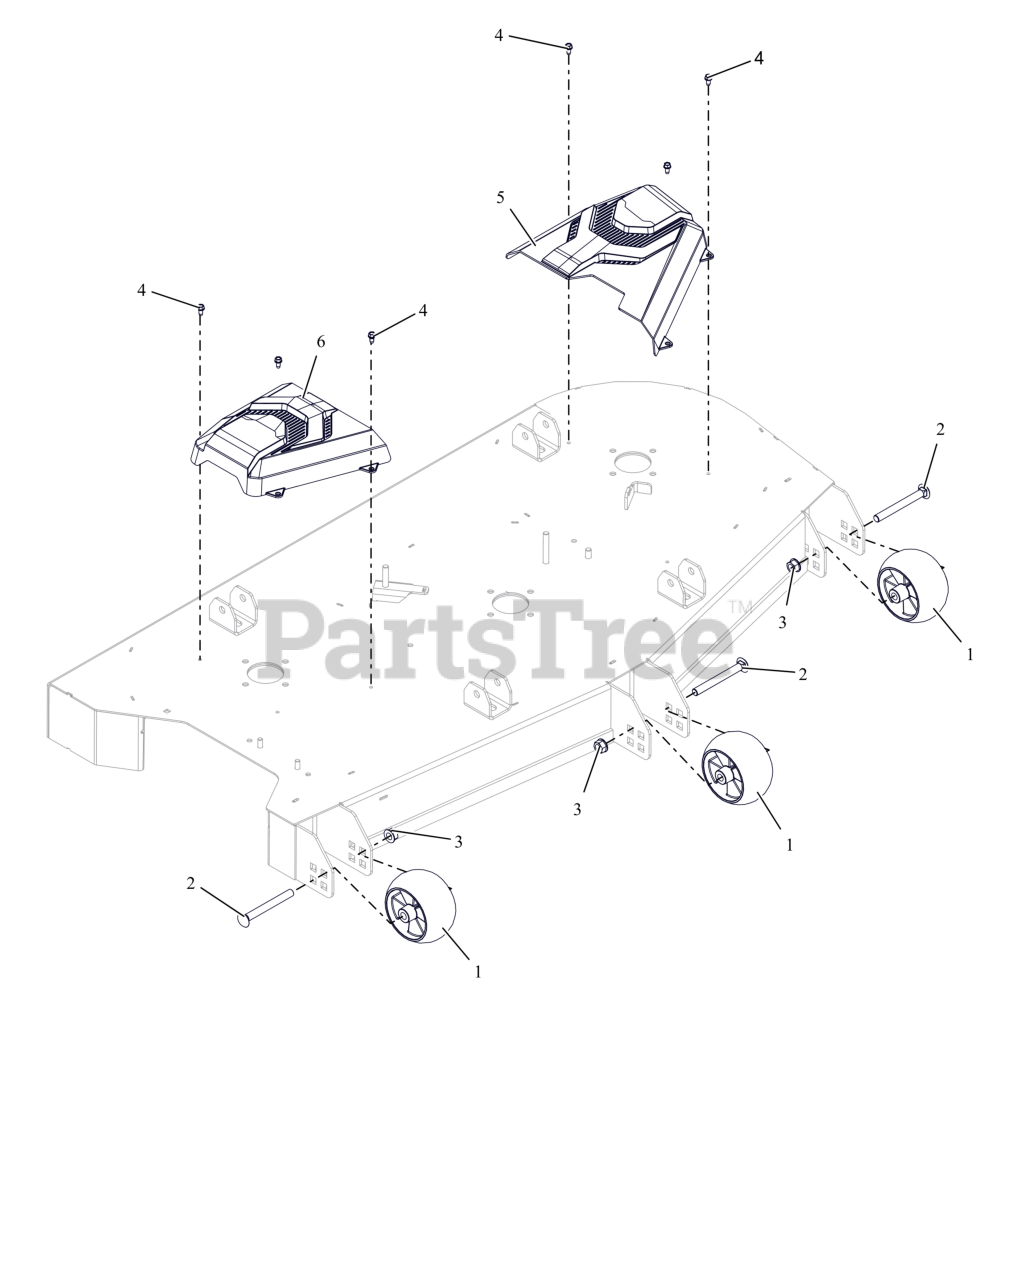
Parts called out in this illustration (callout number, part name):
1	WHEEL, ANTI SCALP - 5X3 CTR W/RIBS
2	BLT-RHNS .50-13X4.50 G5 ZCC NS
3	NUT-LK-CTR-FLG .500-13 GG ZCC
4	SCR-TAP .25-20X.50 HWH ZCC
5	COVER- BELT LH
6	COVER- BELT RH
